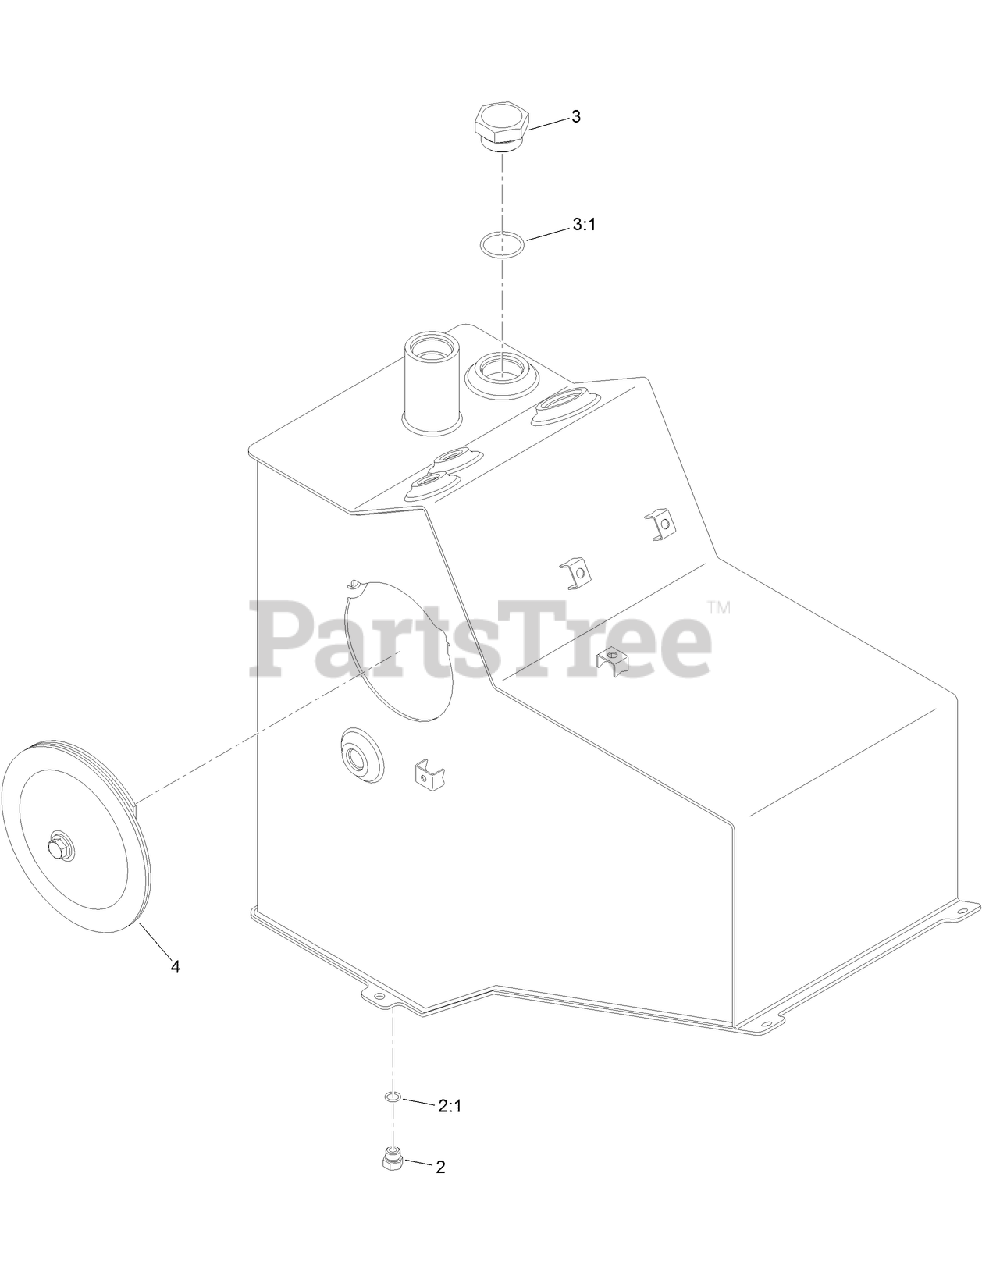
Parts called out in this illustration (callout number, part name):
2	PLUG-HH
2:1	O-RING
3	PLUG-HH
3:1	O-RING
4	CLEANOUT-TANK, HYDRAULIC
